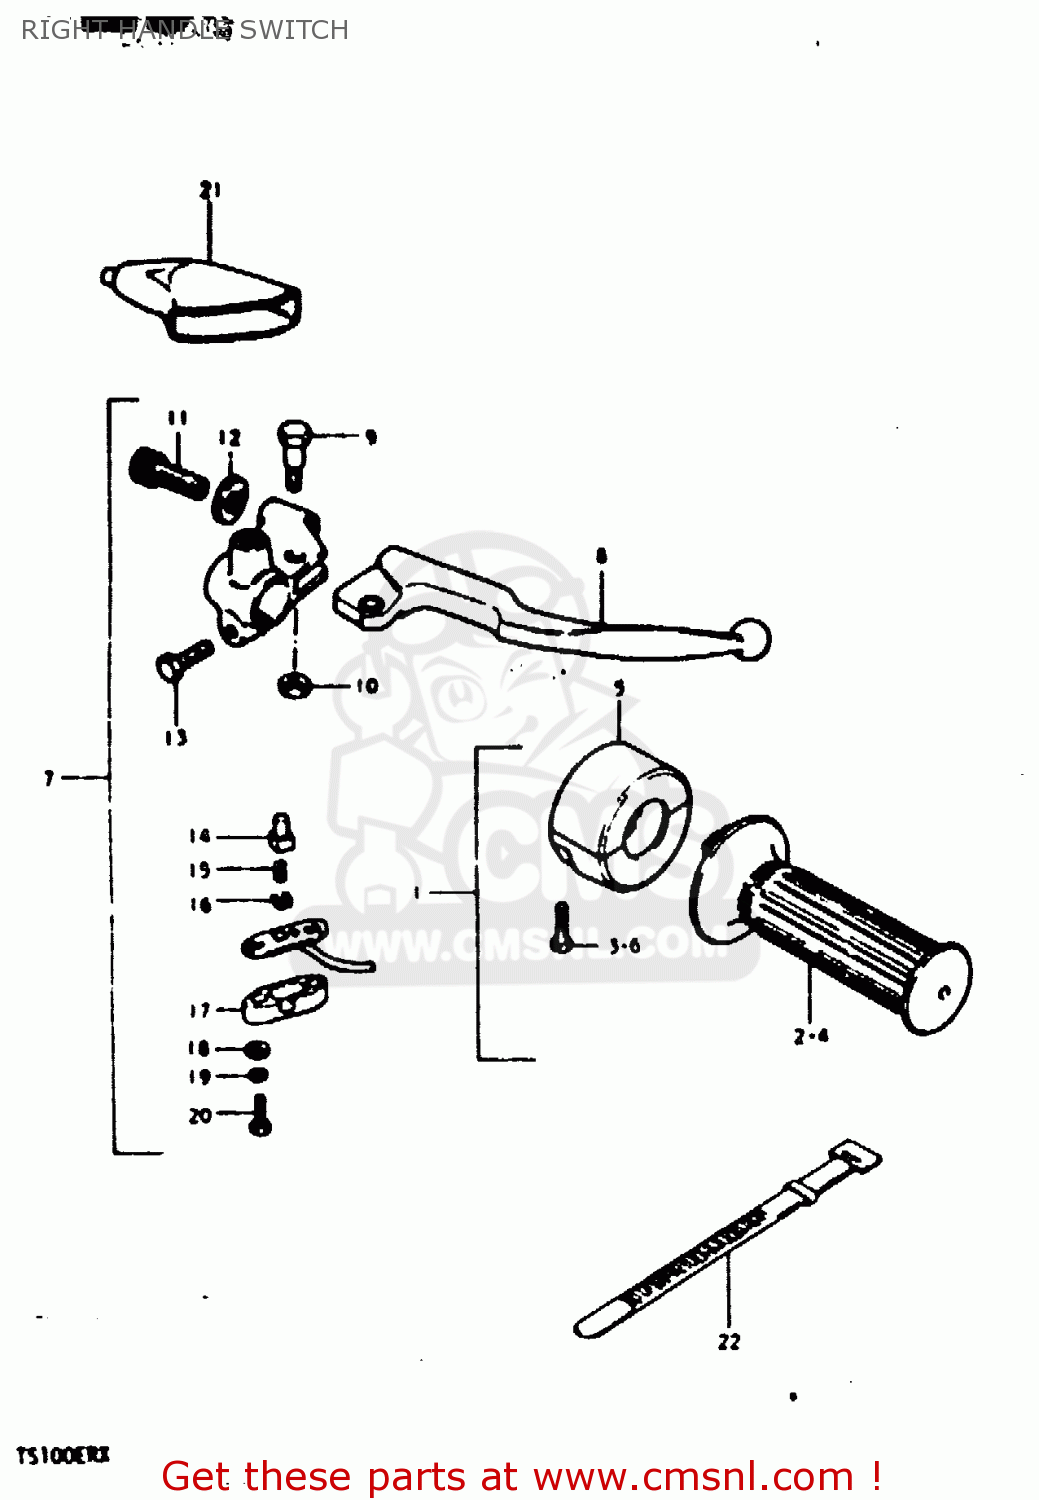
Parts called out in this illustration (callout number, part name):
1	GRIP ASSY, THROTTLE
2	GRIP,THROTTLE
3	SCREW
4	GRIP,THROTTLE
5	CASE ASSY,THROTTLE
6	SCREW
7	LEVER ASSY,BRAKE
8	LEVER,BRAKE
9	BOLT,LEVER
10	NUT 6MM
11	ADJUSTER,CABLE
12	NUT,CABLE ADJUSTER
13	BOLT
14	HOLDER
15	SPRING
16	PLATE
17	COVER,FR BK TERMINAL BASE
18	WASHER
19	LOCK WASHER
20	SCREW
21	COVER,CLUTCH LEVER
22	CLAMP(L:120)
